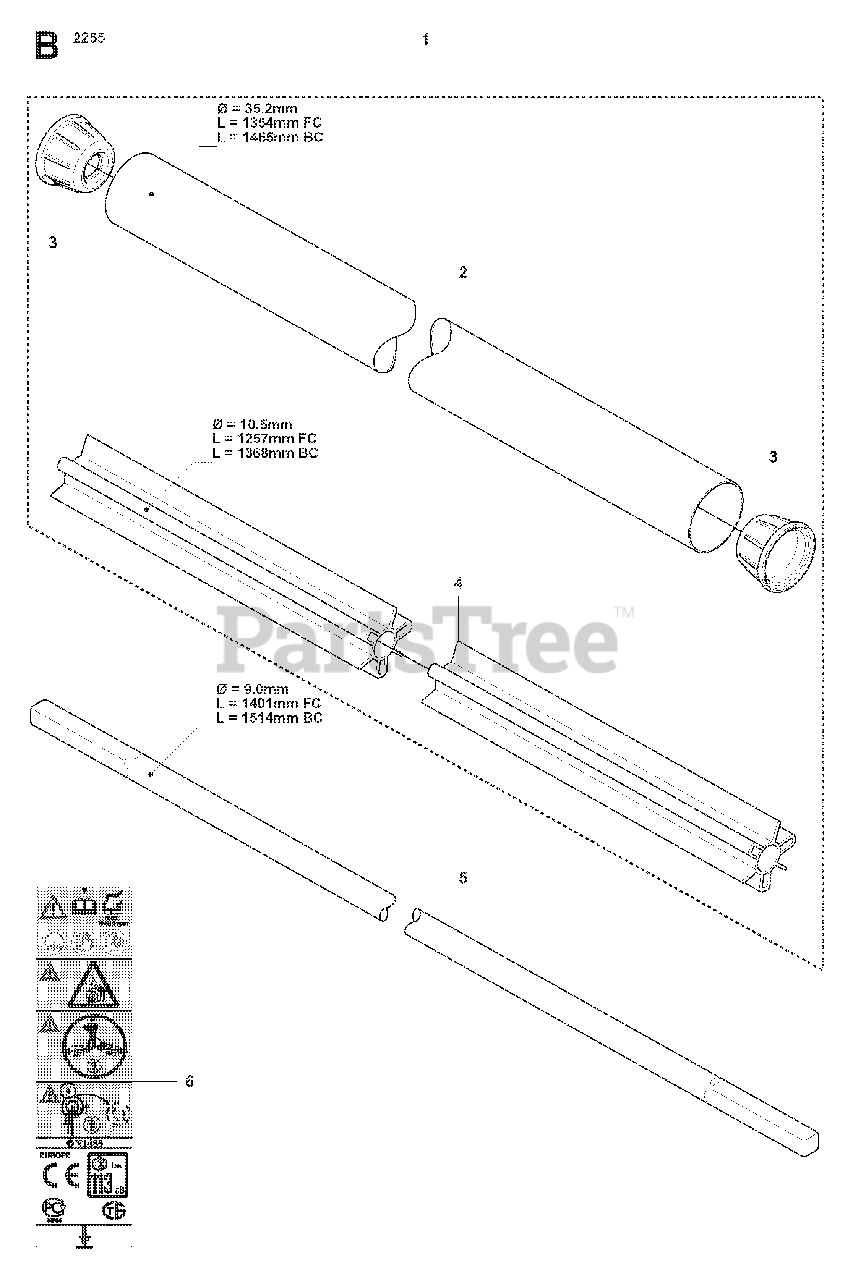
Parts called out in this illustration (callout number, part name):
1	TUBE ASSY
2	TUBE
3	RP SPACER
4	RP BEARING SHAFT
4	%BEARING SHAFT
5	DRIVE SHAFT
